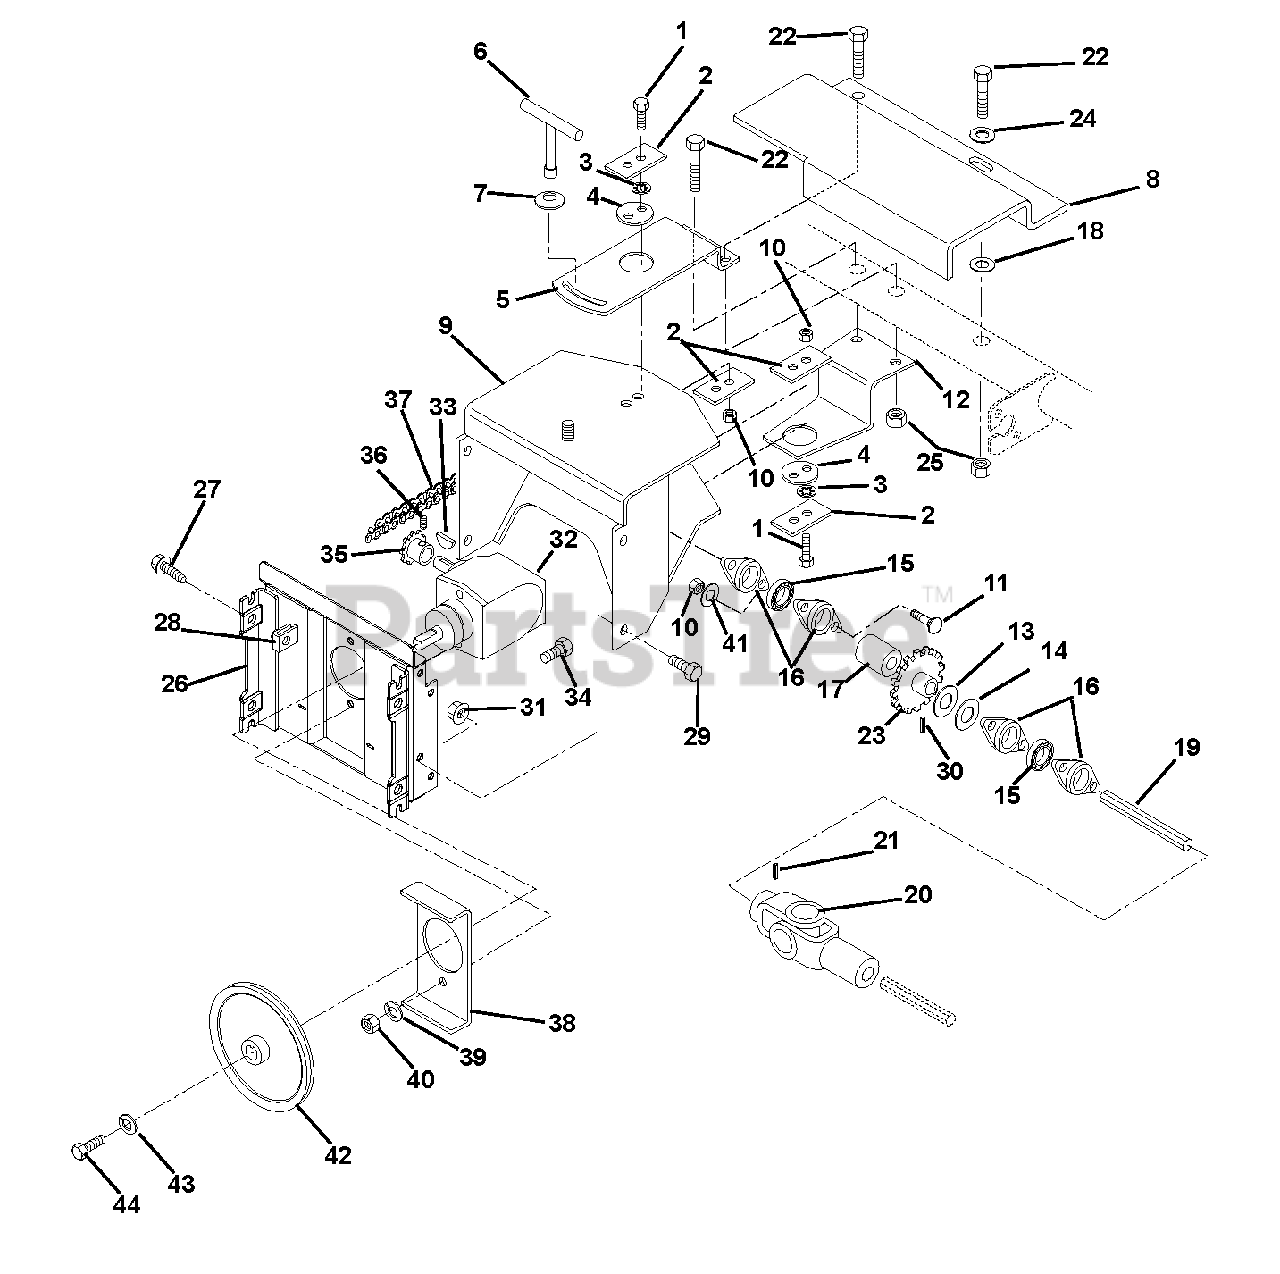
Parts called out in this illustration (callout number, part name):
1	Bolt, Hex .31-18 x 1.25 Grade 5
2	Retainer
3	Washer, Locking External .326 x .599 x .031
4	Pivot, Center
5	Plate, Top Mount
6	T-Lock Handle
7	Washer, Bellville .63 x 1.625 x .14
8	Guard, Shaft
9	Frame, Adapter
10	Nut, Locking Center .31-18
11	Bolt, Round Head Square Neck .31-18 x .75 Grade 5
12	Plate, Bottom Mount
13	Washer, Flat Steel 1.031 x 1.625 x .188
14	Washer, Flat Steel 1.03 x 1.31 x .105
15	Bearing, Ball
16	Flange, Bearing
18	Washer, Flat Steel .390 x .88 x .18
20	Universal Joint
21	Pin, Roll .188 x 1.50
22	Bolt, Hex .38-16 x 3.25 Grade 5
23	Sprocket
24	Washer, Flat Steel .406 x .812 x .065
25	Nut, Locking Center .38-16
26	Plate, Mounting Broom
27	Bolt, Hex Flanged Whizloc Head .38-16 x .75
28	Nut, Retainer .38-16
29	Bolt, Hex .38-16 x .75 Grade 5
30	Pin, Roll .188 x 1.75
31	Nut, Locking Center .38-16
32	Gear Box Assembly
33	Key, Woodruff .188 x .75 x .313 SAE 9
34	Bolt, Hex .38-16 x 1.25 Grade 5
35	Sprocket
36	Screw, Set .25-20 x .38 Socket Head Cup Point
38	Plate, Stiffener
39	Washer, Lock .38 x .094
40	Nut, Hex .38-16
41	Washer, Flat Steel .38 x .875 x .083
42	Pulley, 4L with Hub
43	Washer, Lock .312 x .097
44	Bolt, Hex .312-24 x .75 Grade 5
